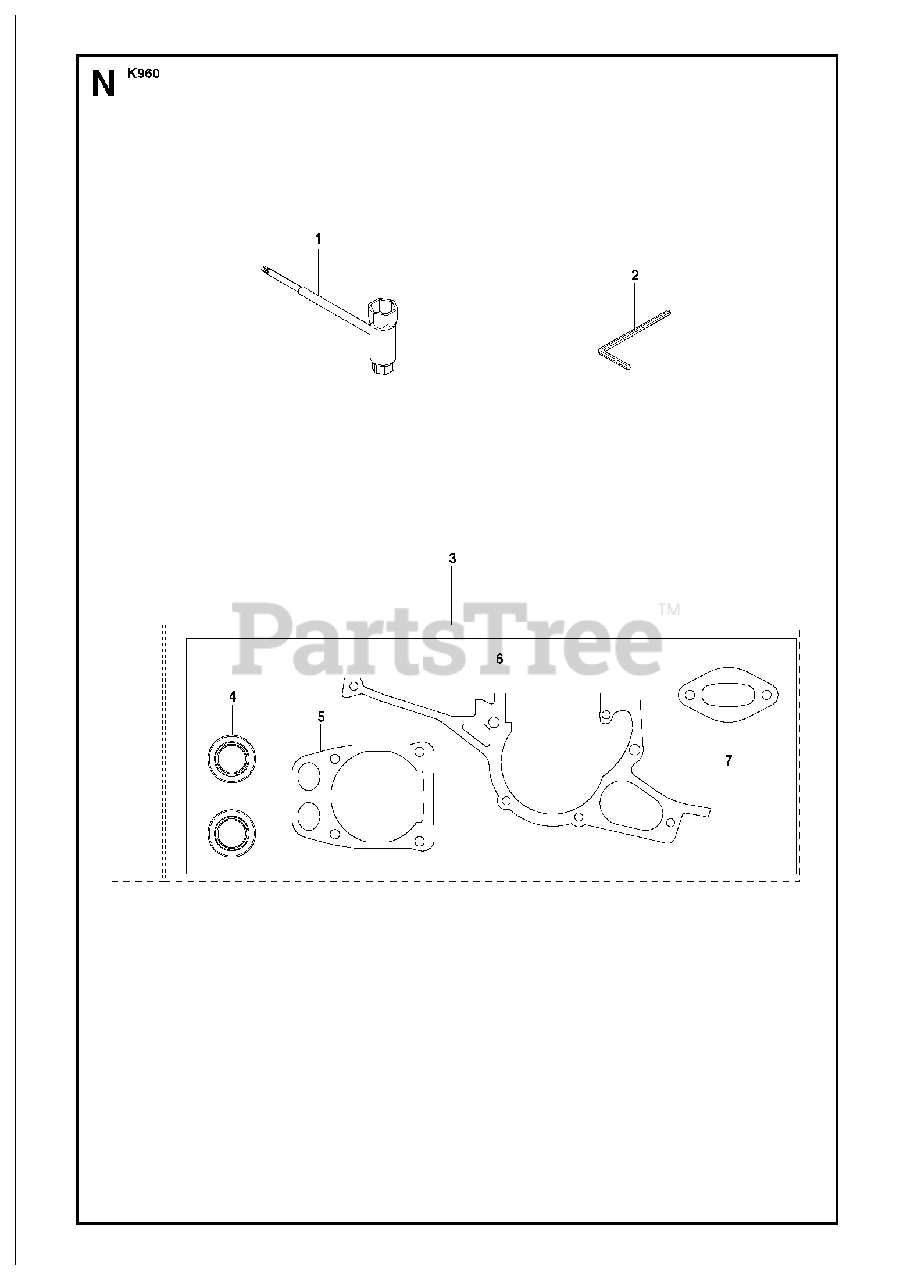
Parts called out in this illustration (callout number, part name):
3	GASKET KITIncl. 4, 5, 6, 7
4	SEALING RING
5	GASKET
7	GASKET
